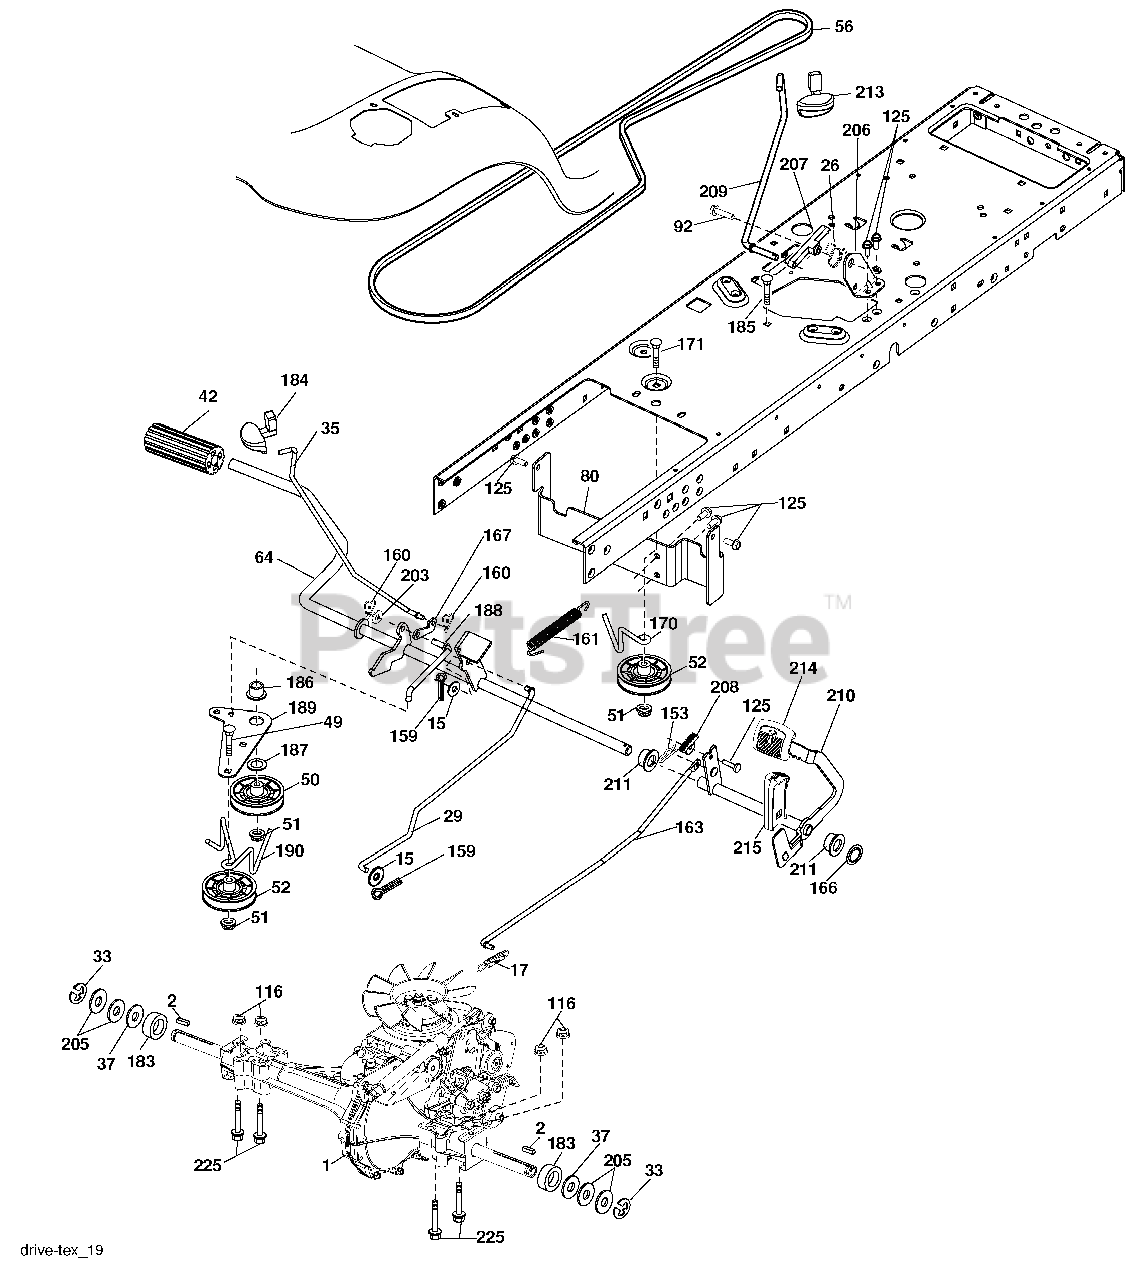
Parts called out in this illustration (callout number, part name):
2	Key
15	Washer 13/32 x 13/16 x 16 Ga.
17	Spring, Brake
26	Spring Return Cruise
29	Rod, Brake
33	Ring E
35	Rod, Brake, Park
37	Washer 25/32 x 1-1/4 x 16 Ga.
42	Cover, Foot Pedal
49	Bolt
50	Pulley Idler Flat
51	Lock Nut 3/8-16
52	Idler V-Groove 910" Offset
56	V-Belt, Drive
64	Shaft Asm. Pedal Brake Control
80	Bracket Strap Torque
92	Bolt Fin Hex 5/16-18 unc x 1.25
116	Nut Lock Hex Flange 5/16-18
125	Screw 5/16-18 x 3/4
153	Retainer Spring
159	Pin Cotter 1/8 x 3/4
160	Retainer Clip
161	Spring, Return, Clutch
163	Rod Pedal Control
166	Nut Push .625
167	Latch Brake Parking
170	Keeper Belt Centerspan
171	Bolt
183	Spacer Axle
184	Handle Parking Brake
185	Bolt
186	Spacer Retainer
187	Washer
188	Link Clutch Ground Drive
189	Bellcrank Ground Drive
190	Keeper Bellcrank Ground Drive
203	Washer 11/32 x 11/16 x 16 Ga.
205	Washer 25/32 x 1-5/8 x 16 Ga.
206	Bracket Mount Latch Cruise
207	Latch Control Cruise
208	Gear Sector Control Cruise
209	Rod Control Cruise
210	Rockr Asm. Pdeal Control
211	Bearing Nylon
213	Knob control Cruise
214	Pad Pedal Forward
215	Pad Pedal Reverse
225	Bolt Hex 5/16-18 x 3.75
